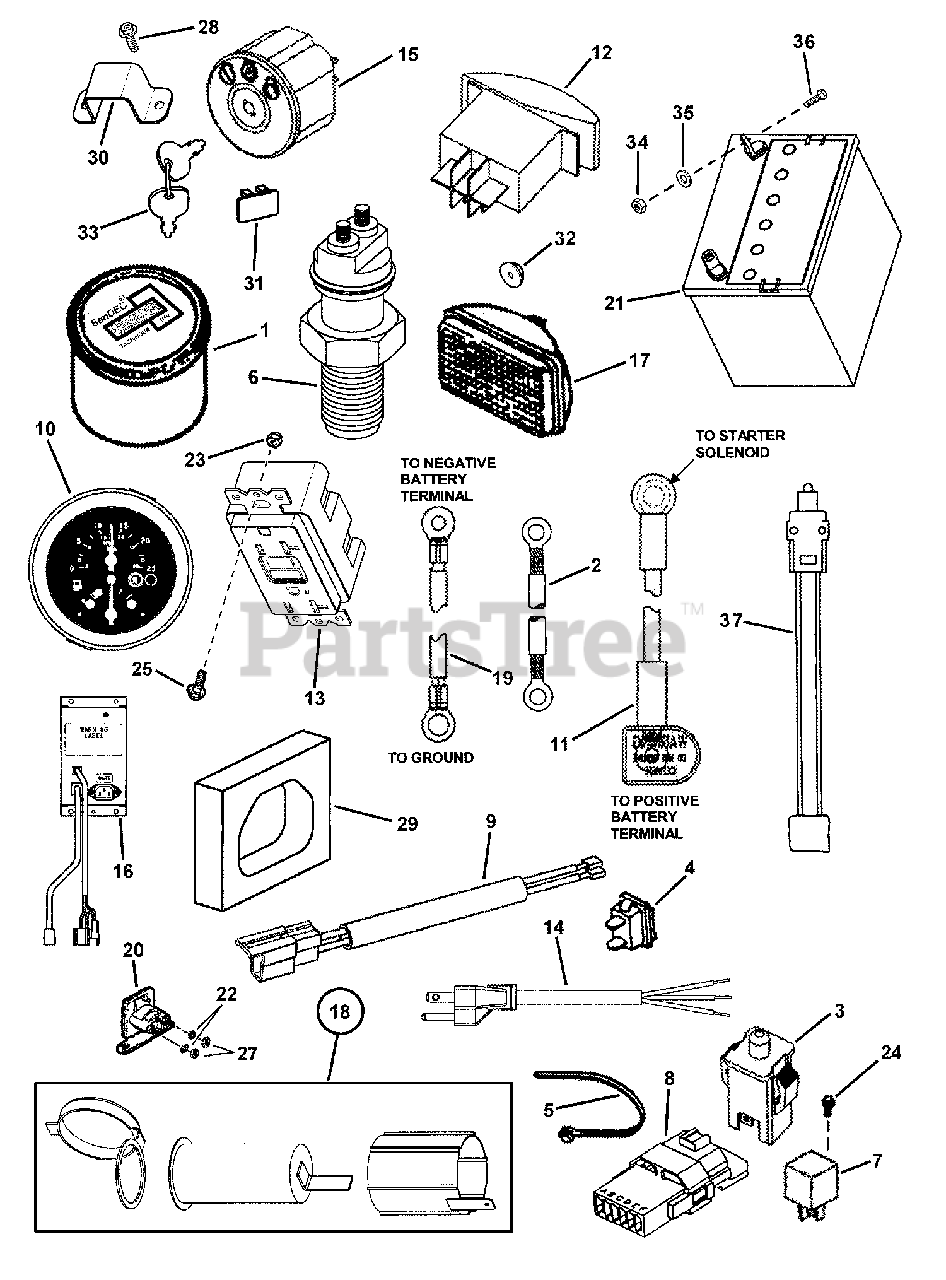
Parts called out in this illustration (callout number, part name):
1	HOUR/TACH METER, Inductive
1	HOUR/Tachometer
2	WIRE, Positive 17"
3	SWITCH, DP NO/NO, Snap-In
4	SWITCH- Rocker SPST
5	WIRE TIE, 11 Inch Std Black Nylon
6	SENSOR, Speed
7	RELAY, OPC E.C.
8	INTERLOCK, UV2, B&S
9	* WIRING HARNESS, UV2 Generator
10	GAGE PACKAGE, Speed/Gas
11	CABLE, Battery, Positive, 24" w/terminal cover
12	SWITCH, Lights
13	* OUTLET, Utility Vehicle
14	* ELECTRIC CORD with Plug
15	SWITCH, Ignition
16	* INVERTER BOX, 120 VAC Powerlink
16	* INVERTER, Powerlink
17	HEADLIGHT
18	OUTLET, 12 Volt DC Power
19	CABLE, Battery Ground, Black 23.0" 6 GA
20	SOLENOID, RER, Super-Trombetta
21	BATTERY, 11 Plate 375CCA - Wet
22	WASHER, 1/4" Internal Tooth Lock
23	NUT, #10-32 Hex Nyloc
24	SCREW, #10-24 x 5/8" Hex Washer Flange Self-Tap
25	SCREW, #10-32 x 5/8 Hex Washer Head Machine
27	NUT, 1/4-20 Hex
28	* SCREW, Thread Rolling Tapping
29	* GASKET, Drop Cord/Inverter
30	* CLAMP, Drop Cord Tie Down
31	PLUG, Dash Hole
32	NUT, 1/4 Nylon Non-Threaded
33	KEY SET (2), G.C. Ignition
34	NUT, 1/4-20 Hex Center Lock, GR 5 or B
35	WASHER, .28 x .63 x .06 Flat
36	SCREW, 1/4-20 x 5/8" Hex Head Cap, GR 5
37	SWITCH, Throttle Interlink (NO)
